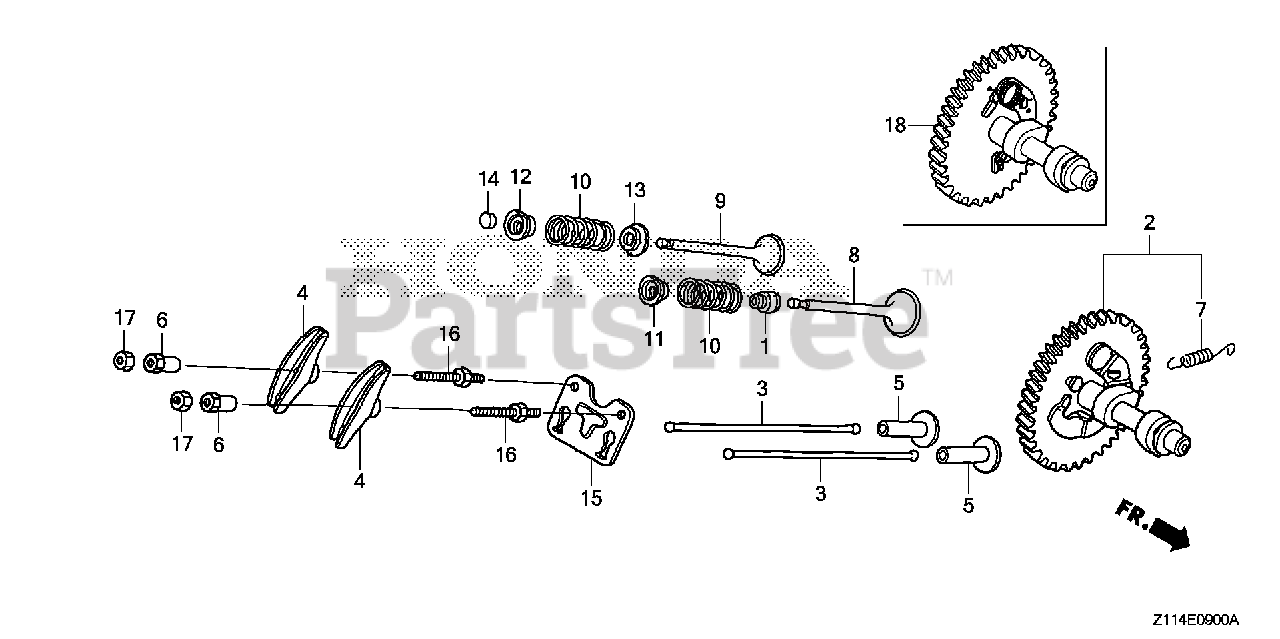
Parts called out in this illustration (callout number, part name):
1	SEAL, VALVE STEM
2	CAMSHAFT (STD) (PRESS FIT CAM)
4	ARM, VALVE ROCKER
5	LIFTER, VALVE
6	PIVOT, ROCKER ARM
7	SPRING, WEIGHT RETURN
8	VALVE, IN.
9	VALVE, EX.
10	SPRING, VALVE
11	RETAINER, IN. VALVE SPRING
12	RETAINER, IN. VALVE SPRING (EXHAUST SIDE)
13	SEAT, VALVE SPRING
15	GUIDE, PUSH ROD
16	BOLT, PIVOT (8MM)
17	NUT, PIVOT ADJUSTING
